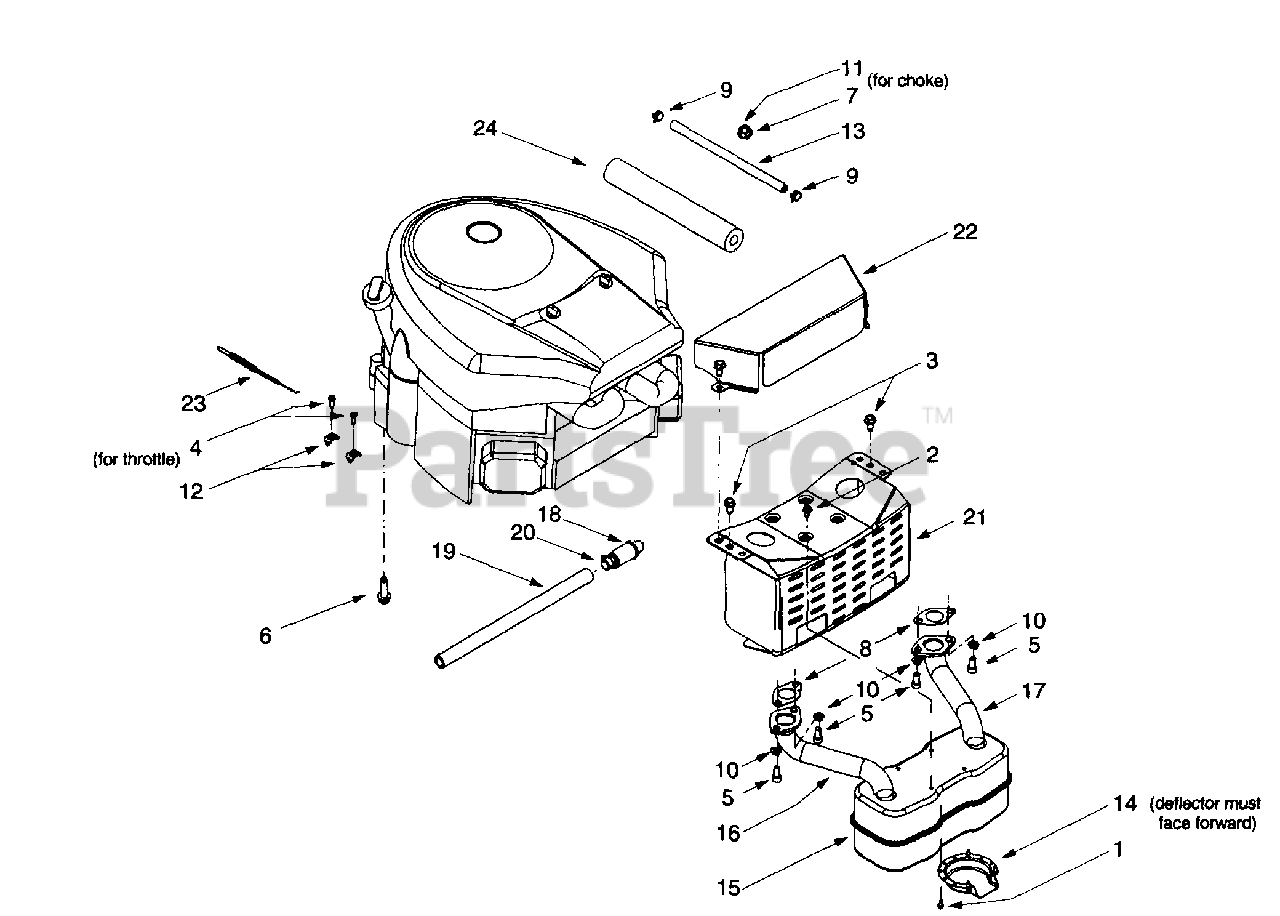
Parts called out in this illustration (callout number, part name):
1	Self Tapping Screw, #8-32 x .375
2	Self Tapping Screw, 1/4-20 x .5
3	Self Tapping Screw, 5/16-18 x .625
4	Screw, #10-32 x .625
5	Socket Cap Screw, 5/16-18 x .625
6	Self Tapping Screw, 3/8-16 x 1.25
7	Hex Nut, 3/8-16
8	Exhaust Gasket
9	Hose Clamp
10	Lock Washer, 5/16
11	Flat Washer, .406 x .875 x .059
12	Casing Clamp
13	Fuel Line Hose
14	Muffler Deflector
15	Muffler
16	RH Exhaust Pipe
17	LH Exhaust Pipe
18	Oil Drain Valve
19	Oil Drain Hose
20	Oil Drain Cap
22	Engine Heat Shield
23	Throttle Cable
24	Foam
